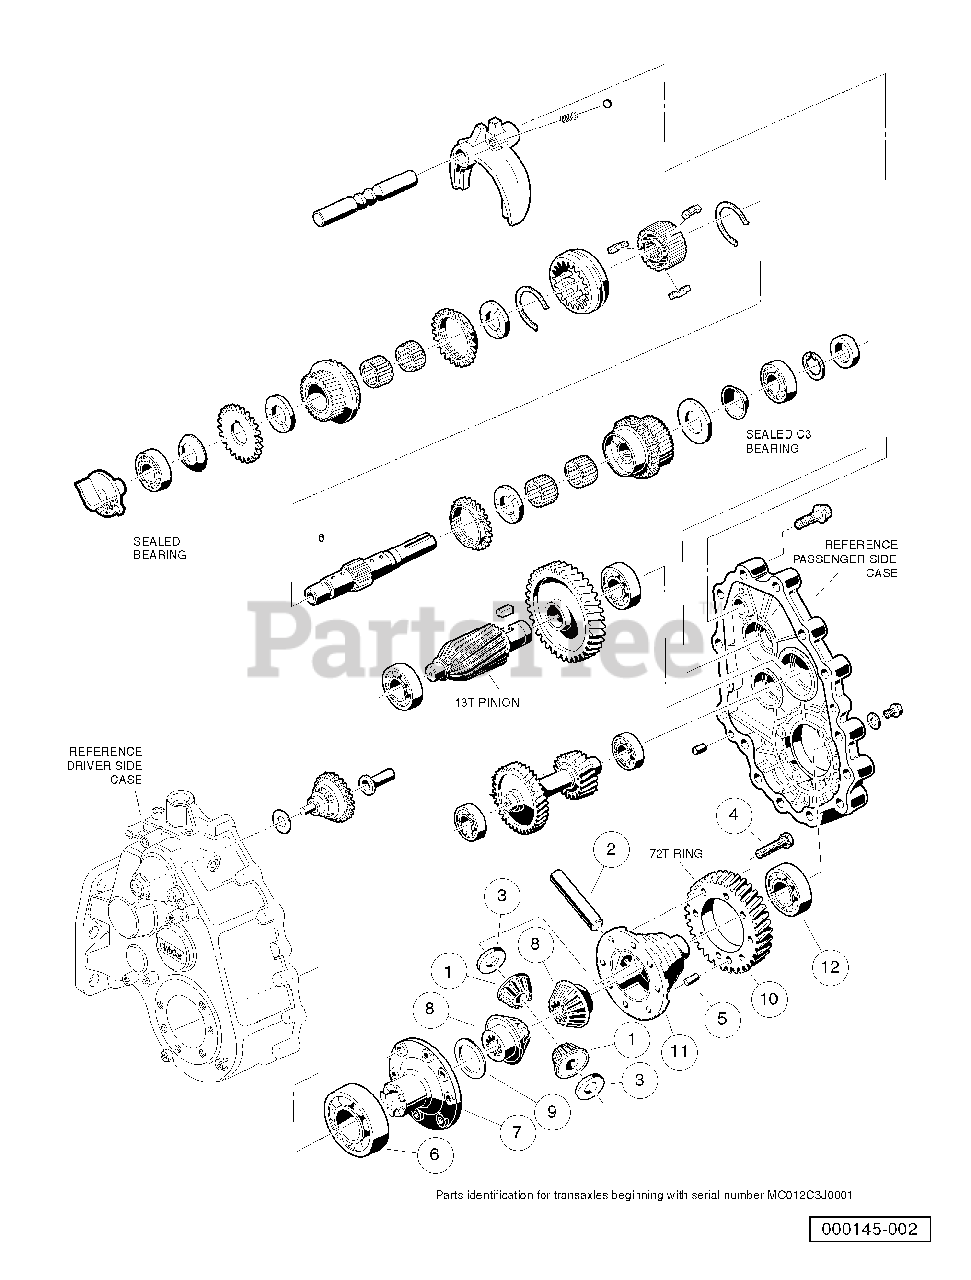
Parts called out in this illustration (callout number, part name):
1	Differential Idler Gear
2	Pin, Differential
3	Plate, Thrust
4	Screw, M8-1.25 X 35mm Hex Head
5	Pin, Dowel
7	Gearcase, LH
8	Gear, Bevel, Side 16-Tooth
9	Plate - Thrust
10	Gear, Helical, Ring, 72-Tooth
11	Case, 72-Tooth Differential Gear Carrier
12	Inner Axle Tube Bearing
